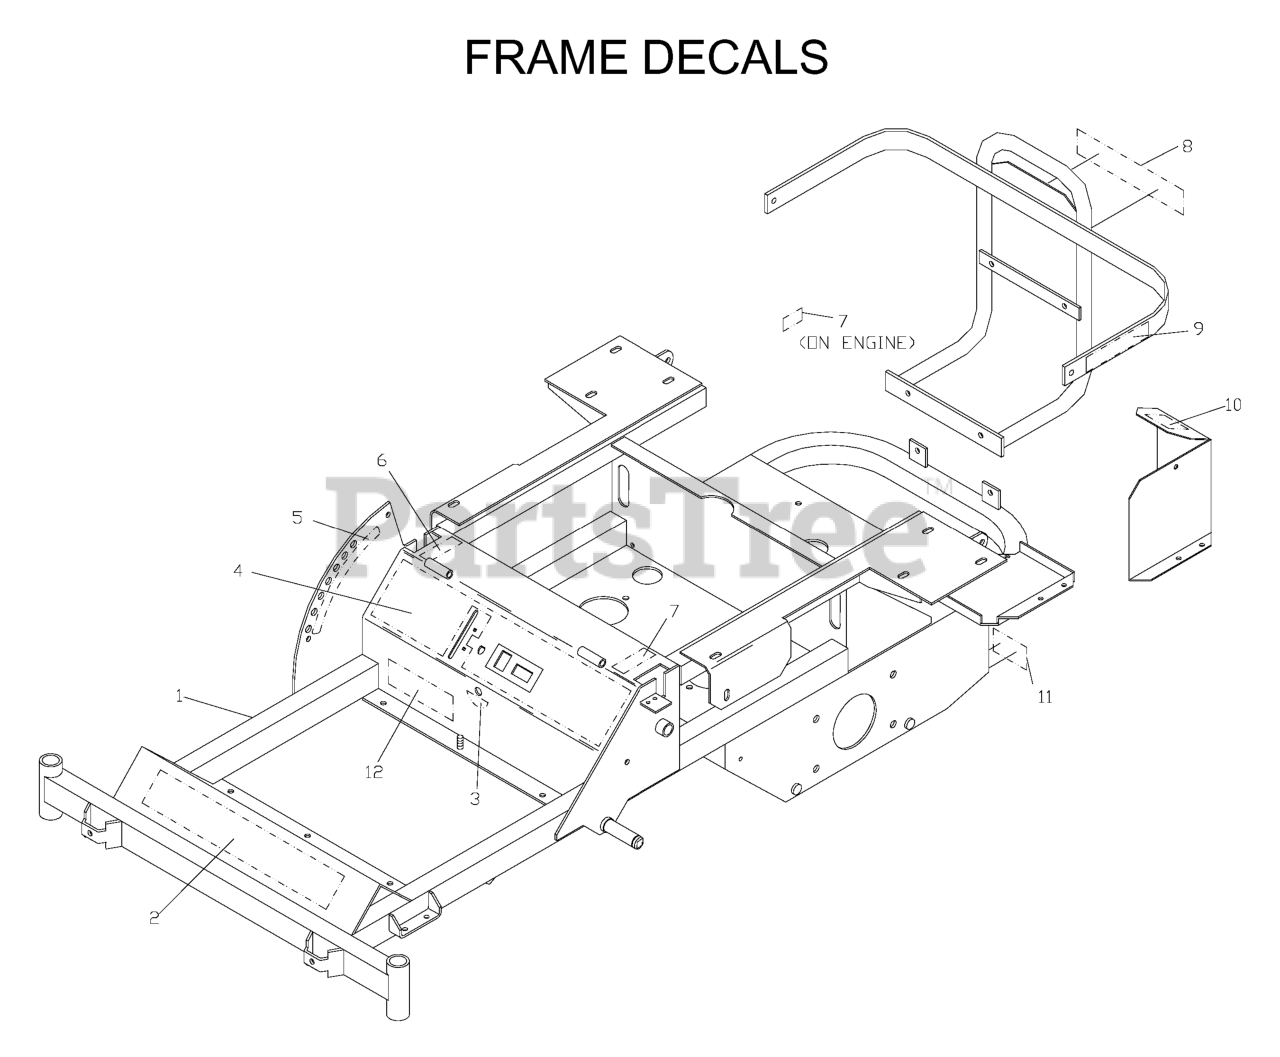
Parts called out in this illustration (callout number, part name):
1	FRAME W/DECALS
2	DECAL, HUSQVARNA 15.5"
3	DECAL, FUEL VALVE
4	CONSOLE DECAL
5	DECAL, LOCATOR
6	DECAL, MOTION CONTROL
7	DECAL, EXHAUST
8	DECAL, HUSQVARNA LOGO 9.25"
9	DECAL, BATTERY
10	DECAL, PROP. 65
11	DECAL, DANGER
12	DECAL, NASCAR
